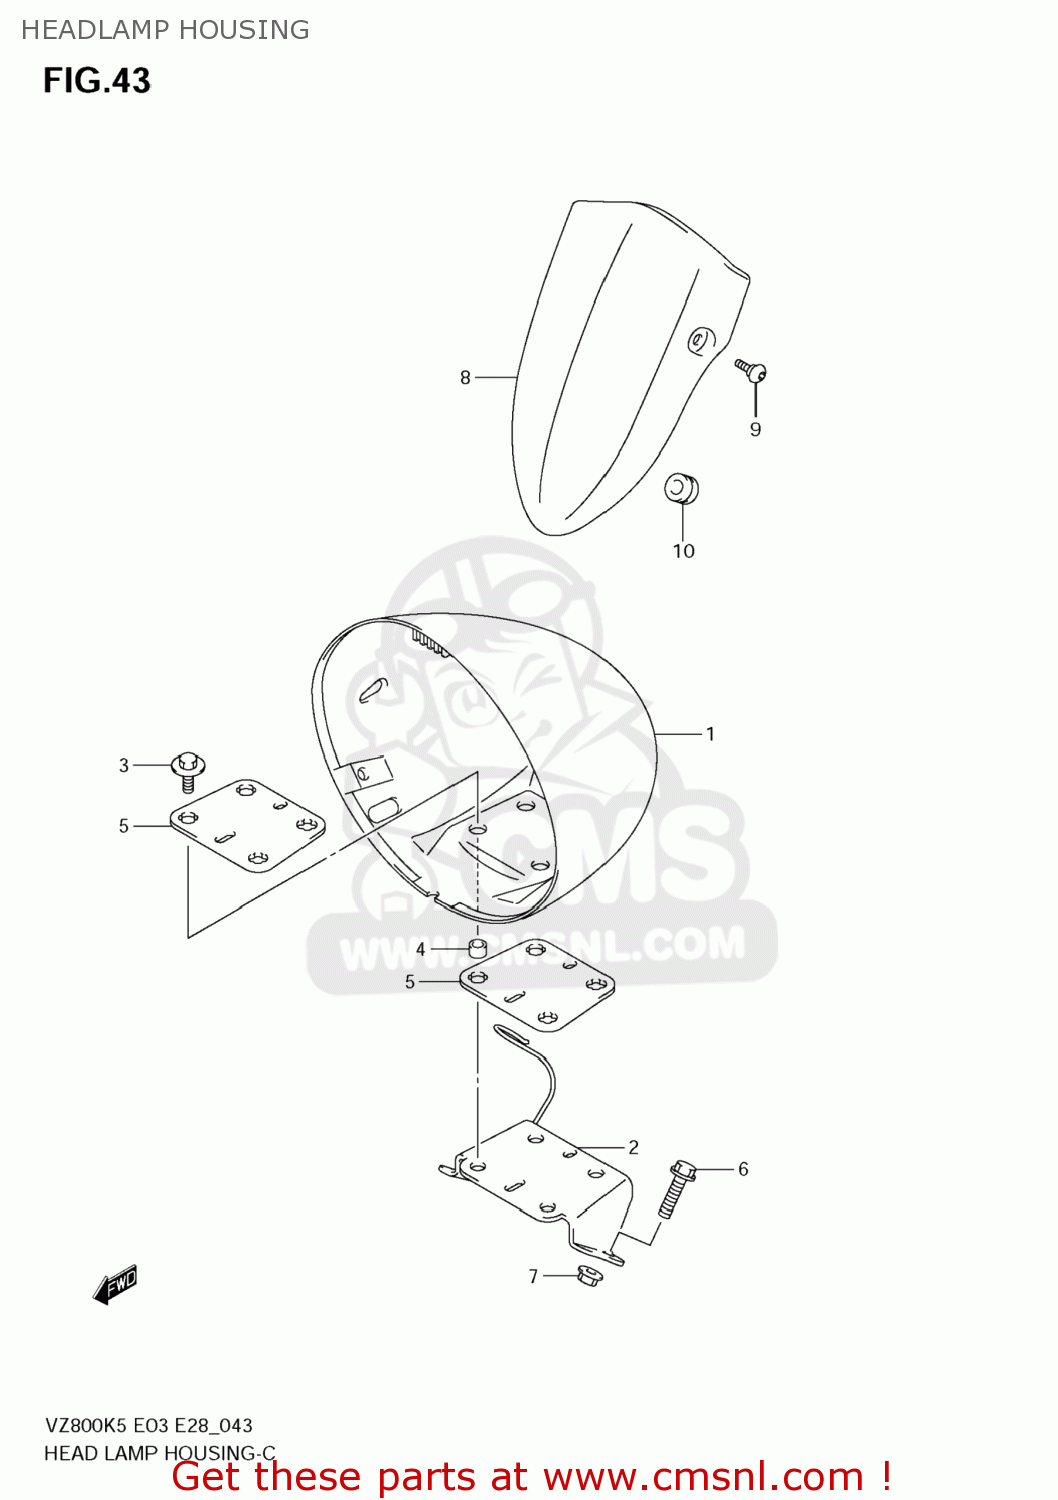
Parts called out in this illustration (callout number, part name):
1	HOUSING HEADLA
2	BRACKET,HEADLAMP HOUSING
3	BOLT(6X20)
4	SPACER(6.8X10X7)
5	CUSHION,HEADLAMP HOUSING
6	BOLT(8X25)
7	NUT
8	COVER,METER
9	SCREW(5X13)
10	CUSHION
